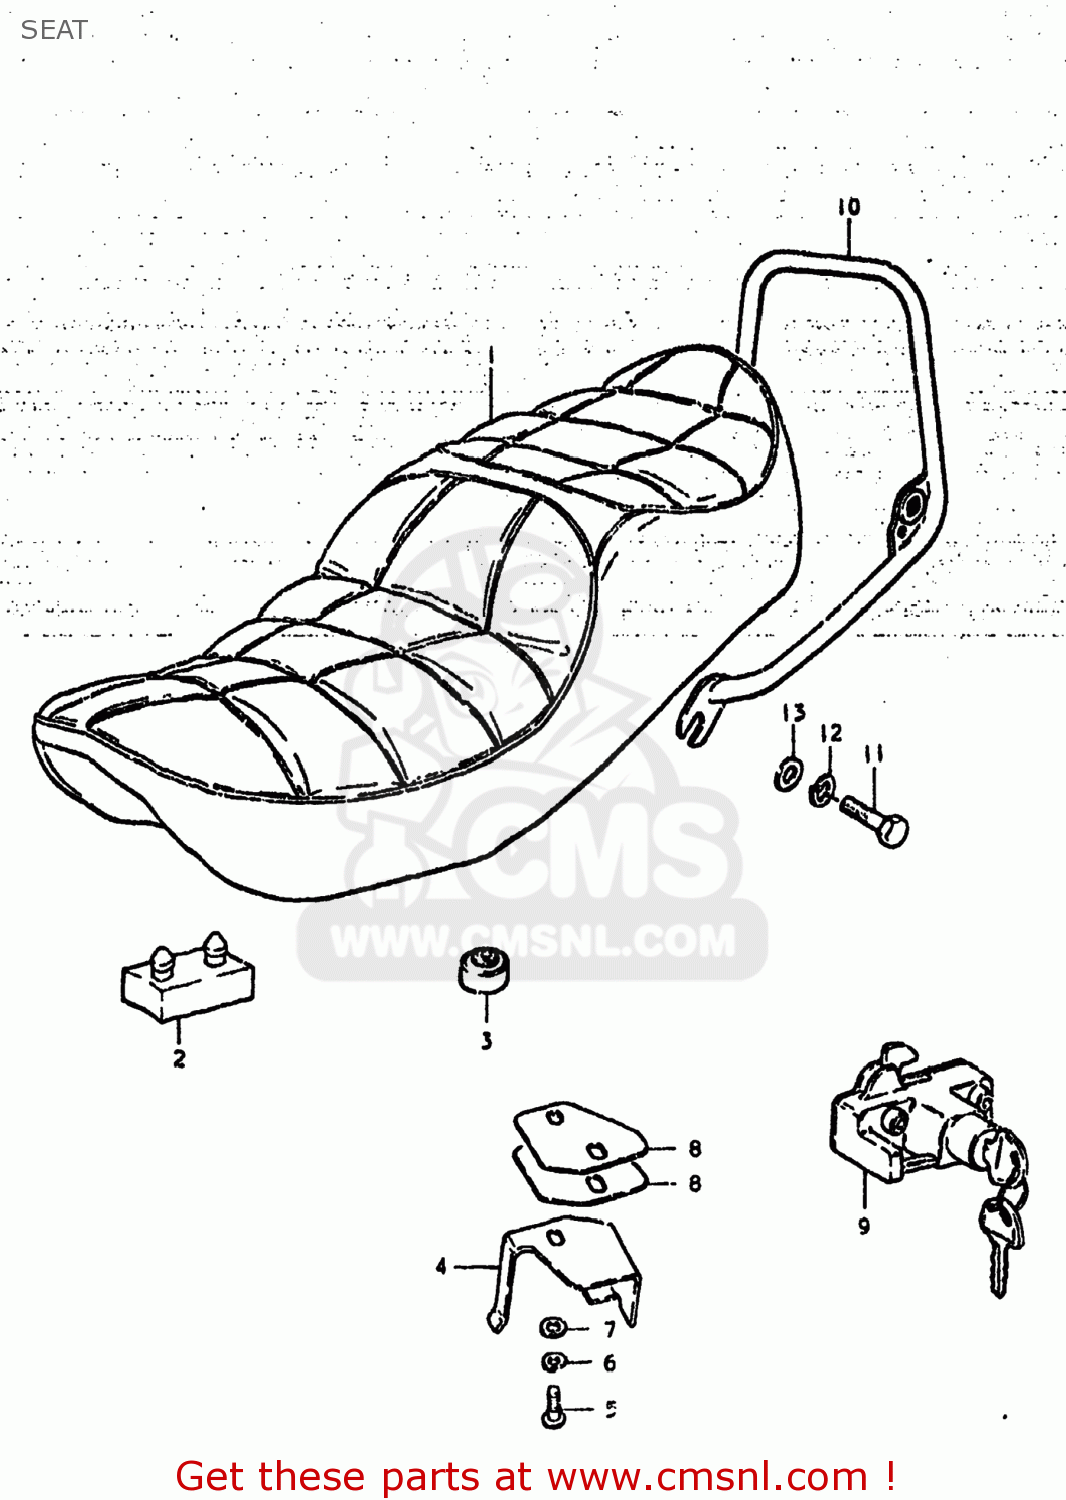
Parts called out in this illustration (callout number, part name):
1	SEAT ASSEMBLY
2	CUSHION
3	CUSHION
5	BOLT, UPPER
6	LOCK WASHER
7	WASHER(6.5X16X1.2)
8	SHIM,SEAT LOCK STRIKER
9	LOCK SET
10	HANDLE,PILLION RIDER
11	BOLT
12	LOCK WASHER
13	WASHER
